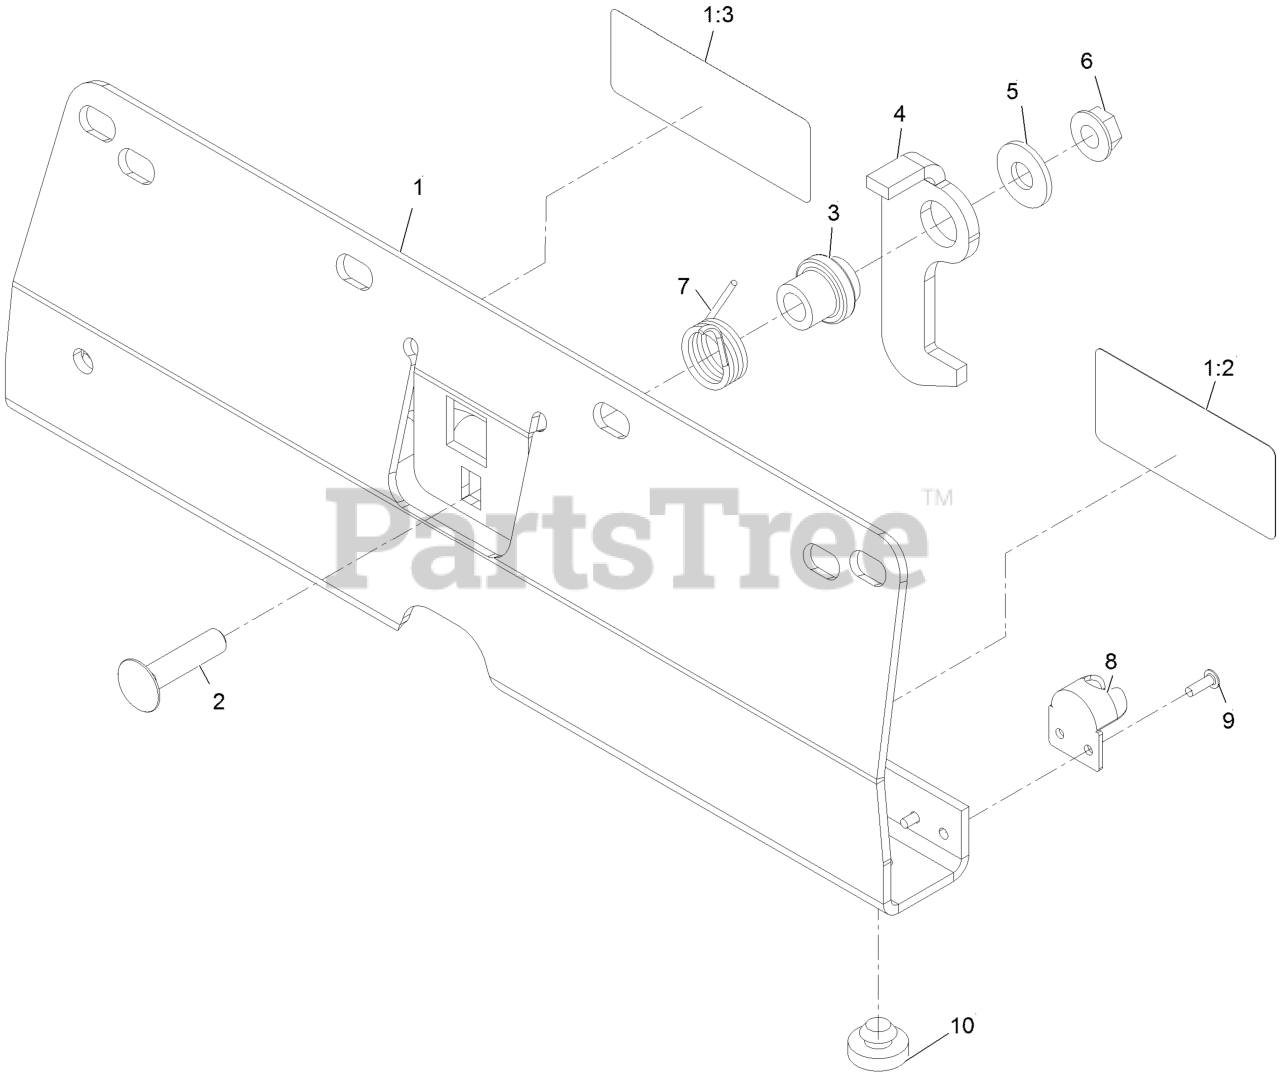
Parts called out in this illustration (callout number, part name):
1	ASM,LATCH PLATE S.O.
1:2	DECAL-ANTIFREEZE
1:3	DECAL,RADIATOR ASSEMBLY
2	SCREW-CARR
3	BUSHING-LATCH, SEAT
4	HOOK,LATCH
5	WASHER-FLAT
7	SPRING,LATCH
